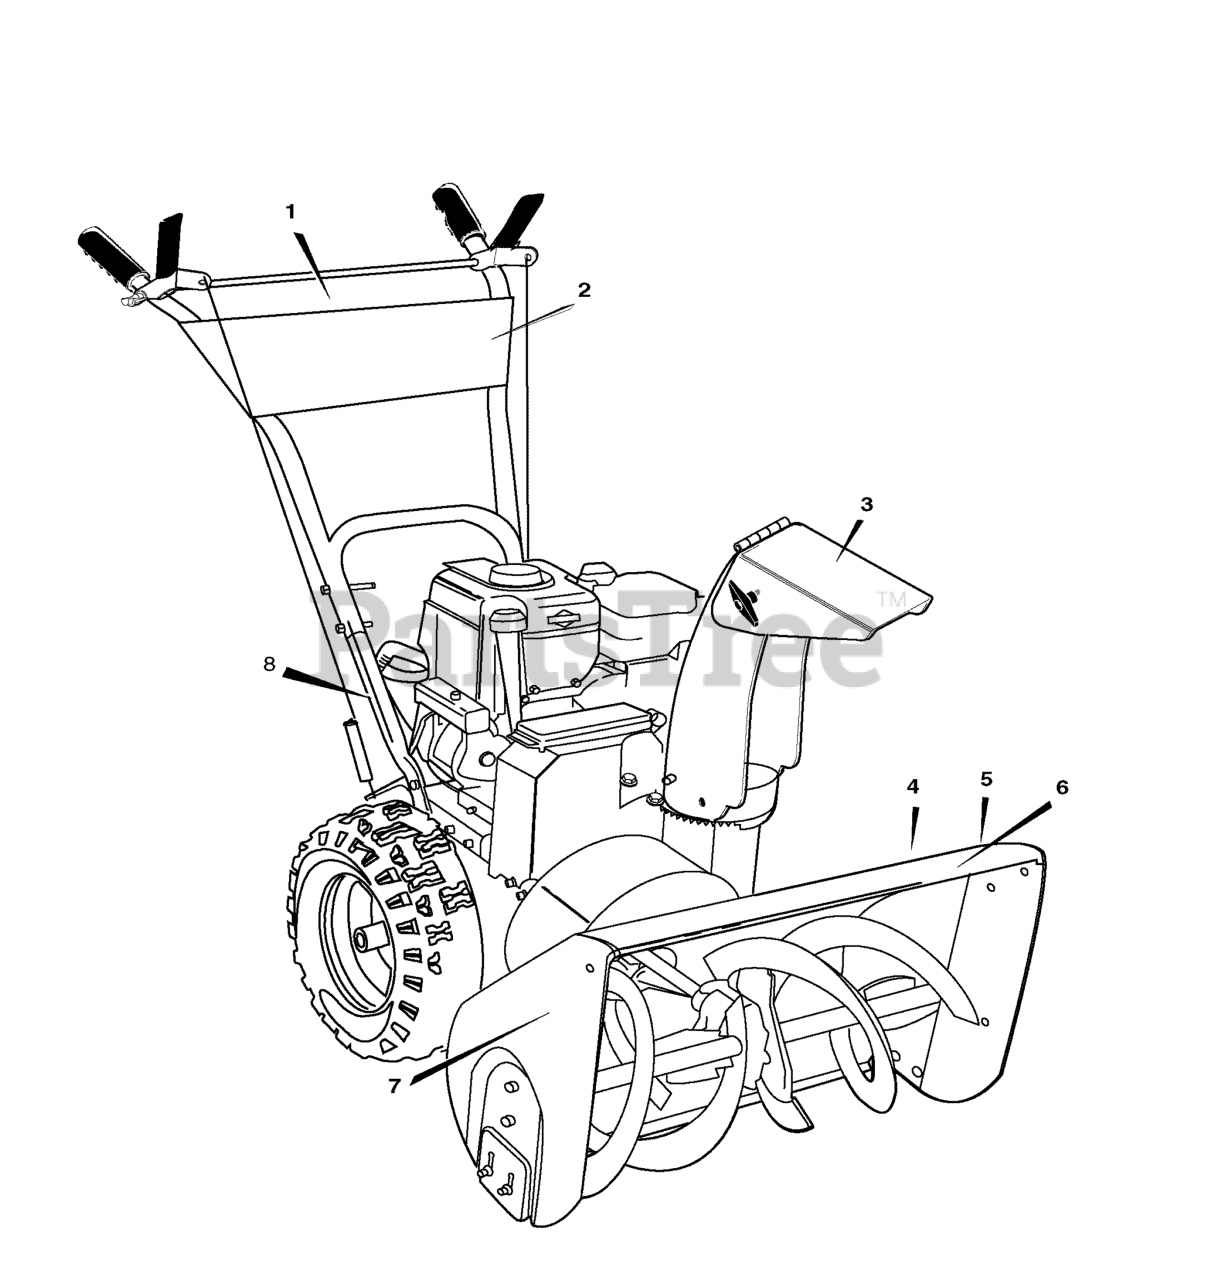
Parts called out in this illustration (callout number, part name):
1	DECAL, HAND CONTROL
2	DECAL, MURRAY ULTRA CONTROL PANEL
3	DECAL, ISO CHUTE CE
4	DECAL, 104db CE
5	DECAL, FACE HEAD PHONES
6	DECAL, MURRAY ULTRA 800/61
7	DECAL, ISO AUGER CE
8	DECAL, GEAR SELECT
